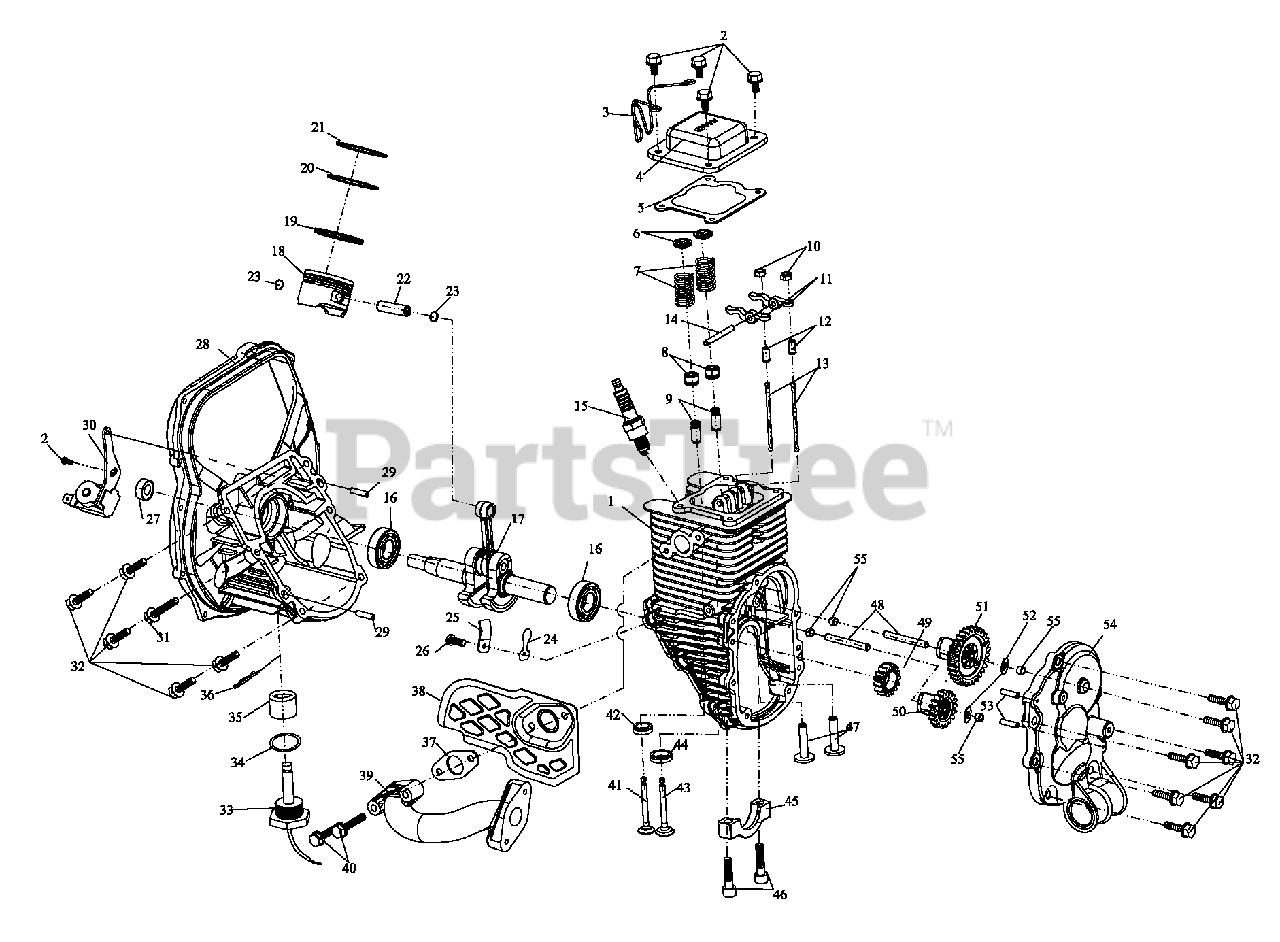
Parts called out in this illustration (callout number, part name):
2	BOLT, HEX FLANGE, M5*10
3	GUARD, SPARK PLUG
4	COVER, VALVE
5	GASKET, VALVE COVER
13	PUSH-ROD, VALVE
15	SPARK PLUG
16	BEARING, DEEP GROOVE BALL
17	CRANKSHAFT & CONNECTING ROD ASSY.
19	RING, OIL
20	COMPRESSION RING, BOTTOM
21	COMPRESSION RING, TOP
22	PIN, PISTON
23	RETAINER (CIRCLIP), PISTON PIN
27	SEAL, CRANKSHAFT OIL (15*27*5)
30	OIL ASSY., TRIGGER
31	BOLT, HEX FLANGE M5*40
32	BOLT, HEX FLANGE M5*18
36	SPRING CLIP
37	GASKET, EXHAUST PIPE
38	WINDSHIELD
39	PIPE, EXHAUST
40	BOLT, HEX FLANGE, M5*25
47	TAPPET, VALVE
48	PIN, CAMSHAFT
49	GEAR, TIMING
50	CAMSHFT GEAR ASSY., EXH VALVE
51	CAMSHFT GEAR ASSY., INTAKE VALVE
52	GASKETS, CAMSHAFT
53	GUIDE PIN, CASE BODY
55	BEARING, OIL RETAINING
